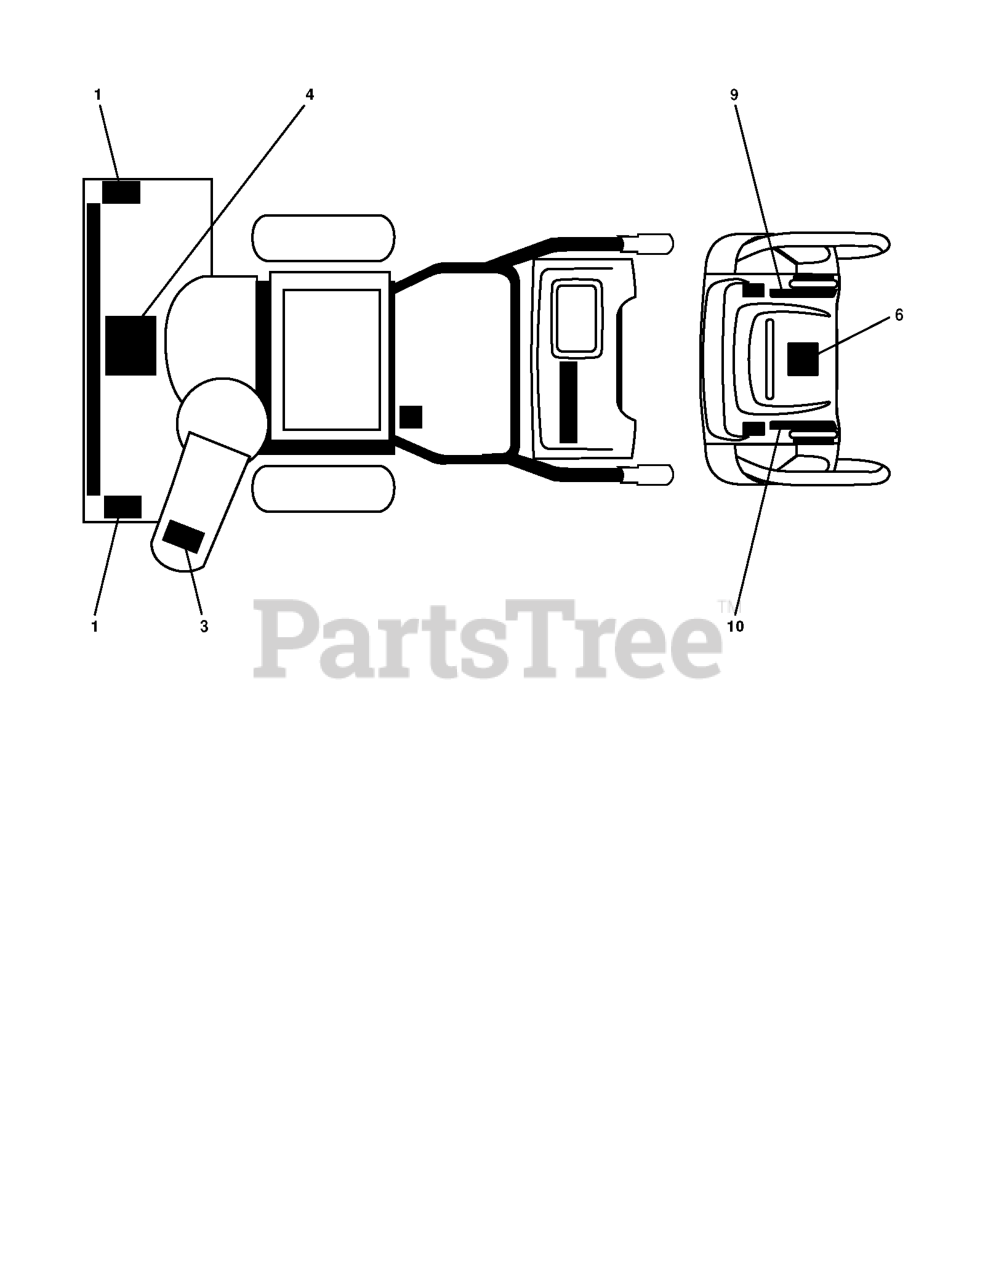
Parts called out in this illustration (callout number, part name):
1	DECAL.SNOWTHR.AUGER
3	DECAL.SNOWTHR.CHUTE.SAFETY
4	DECAL.SNOWTR.READ.OWN.MAN.E/F
6	DECAL.SNOWTR.READ.OWN.MAN.E/F
9	DECAL SPEED CONTROL
10	DECAL, REMOTE DEFLECTOR
